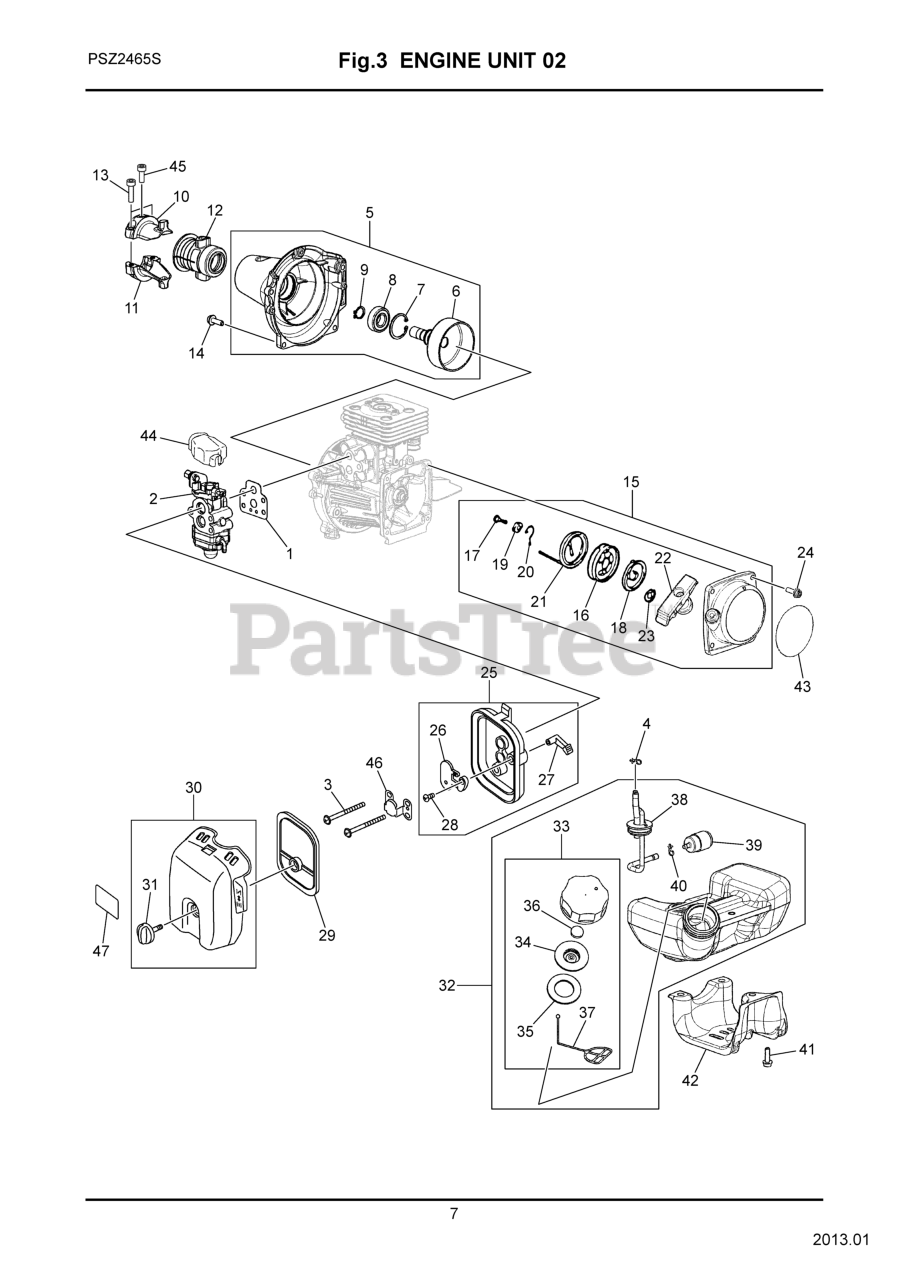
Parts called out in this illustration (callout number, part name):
1	GASKET, CARB (RPLS T155113131)
2	CARBURETOR ASSY
3	BOLT TORX
4	CLIP
5	COVER, C
6	DRUM (RPLS 481031120-22)
10	BRACKET (A) (RPLS T170031211)
11	BRACKET (B)
15	RECOIL ASSY
18	SPRING, SPIRAL
19	COLLAR
20	SWING ARM
23	PLATE.STOPPER
25	CLEANER BODY ASSY
26	PLATE, CHOKE
28	SCREW
29	ELEMENT
30	COVER ASSY
31	Cleaner Knob
32	TANK ASSY
34	HOLDER-A
38	PIPE ASSY
39	FILTER
40	CLIP
43	LABEL, RECOIL
